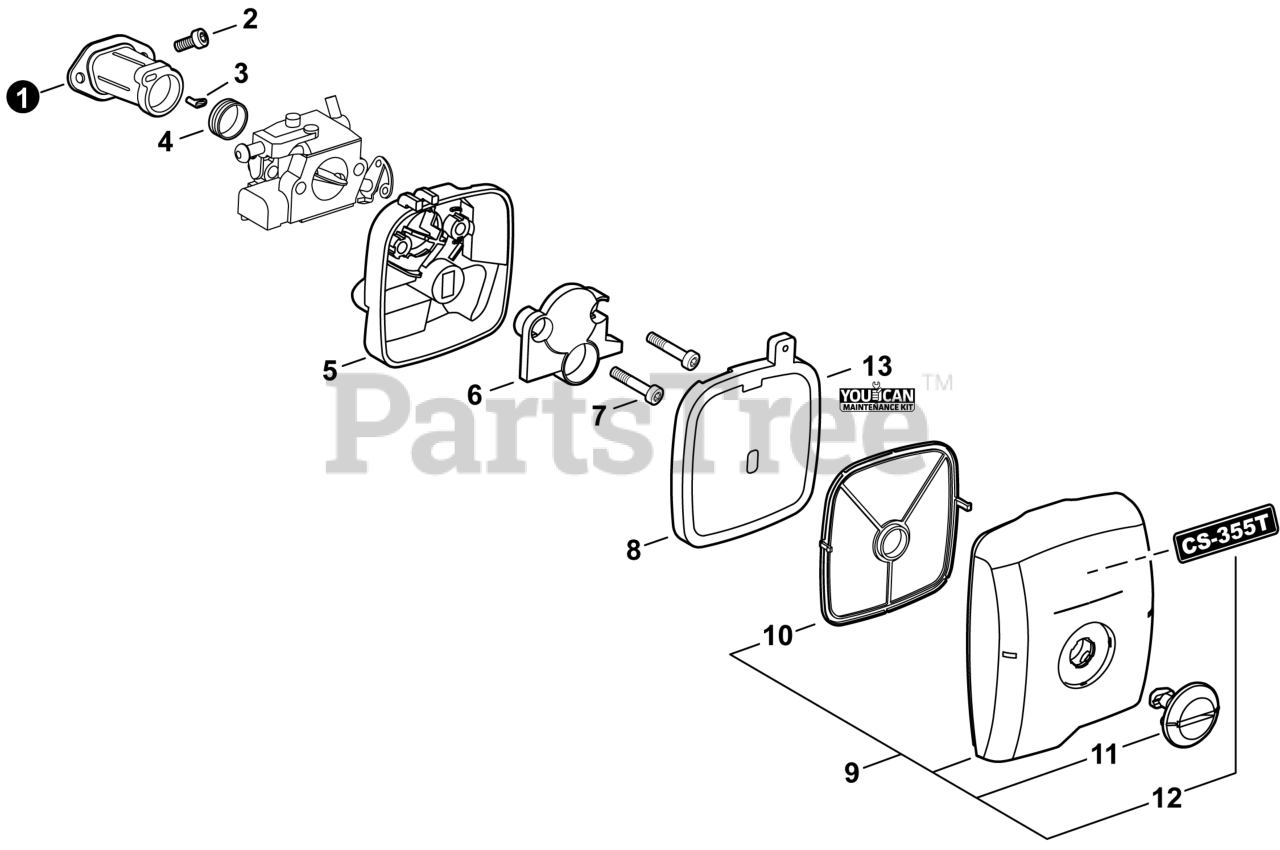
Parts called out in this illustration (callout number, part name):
1	BELLOWS, INTAKE
2	BOLT, TORX 5×12
3	COLLAR Ø3.2×6.5
4	SPRING, TENSION
5	CASE, AIR FILTER
6	PLATE, PREVENT
7	BOLT, TORX 5×50
8	FILTER, AIR
9	COVER ASSY, AIR FILTER
10	SEAL, AIR FILTER
11	KNOB, AIR FILTER COVER
12	LABEL - MODEL CS-355T
13	TUNE-UP KIT - YOUCANT
